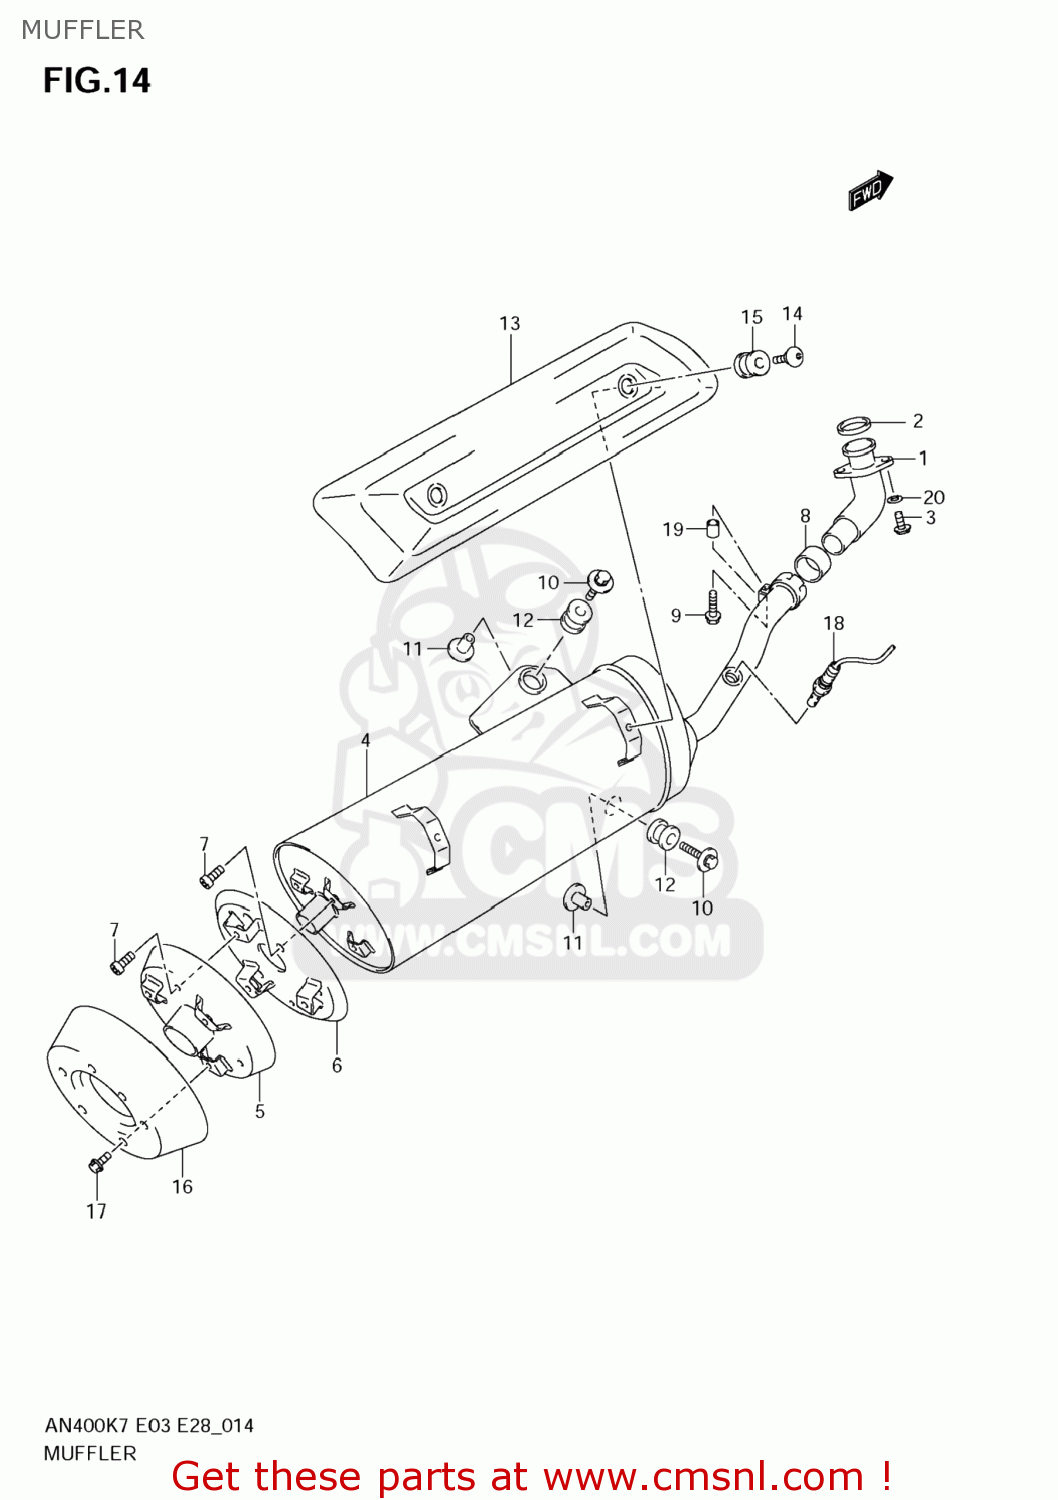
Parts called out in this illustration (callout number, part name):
1	PIPE,EXHAUST
2	GASKET,EXHAUST
3	BOLT
4	BODY,MUFFLER
5	STAY,MUFFLER RR COVER
6	STAY,MUFFLER RR COVER NO.2
7	BOLT(6X10)
8	CONNECTOR,MUFFLER
9	BOLT(8X35)
10	BOLT(8X45)
11	SPACER(8.6X12X24.2)
12	CUSHION
13	COVER,MUFFLER
14	SCREW(6X20)
15	CUSHION
16	COVER,MUFFLER RR
17	BOLT(6X15)
18	SENSOR,OXYGEN
19	SPACER,MUFFLER
20	WASHER
